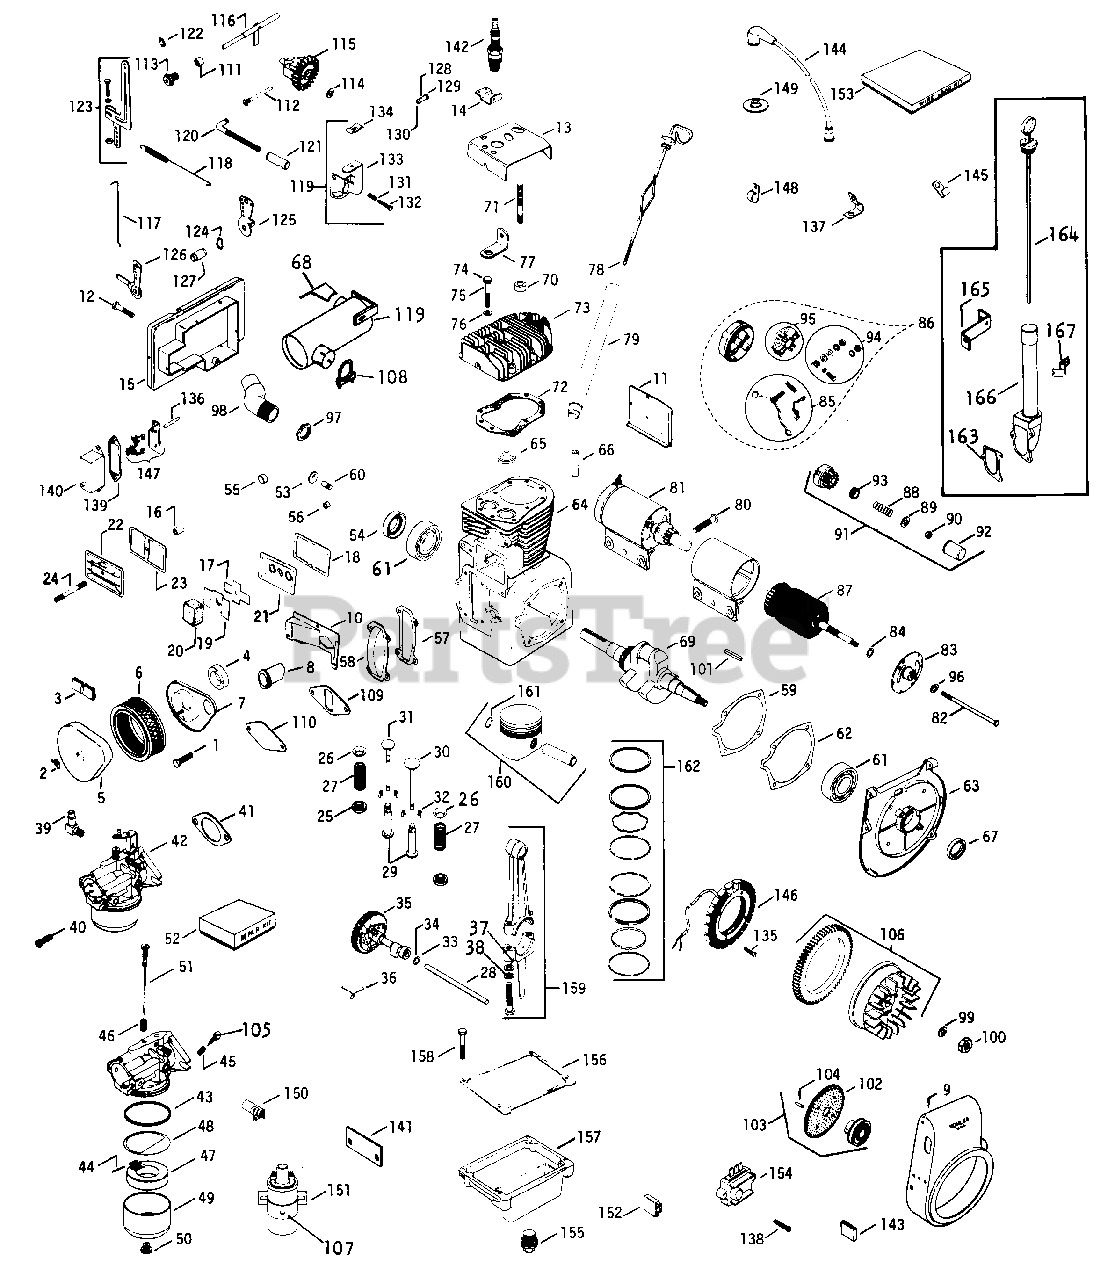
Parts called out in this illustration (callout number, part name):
1	Screw, 10-32 X 1/2 Znd Hex Hd Self Tap
2	Nut, Wing
4	Gasket, Air Cleaner
5	Cover, Air Cleaner
6	Element, Air Cleaner
7	Base, Air Cleaner
8	Tube, Air Cleaner
9	Housing, Blower
10	Baffle, Side
11	Baffle, Cylinder
12	Screw, 1/4-20 X 3/4 Hex Hd
13	Baffle, Head
14	Bracket, Lifting
16	Seal, Breather
17	Reed, Breather
18	Gasket, Cover
19	Baffle, Breather
20	Filter, Breather
21	Plate, Breather
22	Cover, Breather
23	Gasket, Valve Cover
24	Stud, Valve Cover
25	Retainer, Valve Spring
26	Retainer,Valve Spring
27	Spring, Valve
28	Pin, Camshaft
29	Tappet Assy
30	Valve, Intake
31	Valve, Exhaust
32	Keeper, Valve Spring
33	Shim, Camshaft, .005
34	Shim, Camshaft, .010
35	Camshaft Assy
36	Spring, Camshaft Actuating
37	Washer, Connecting Rod
38	Washer, 3/8 Heavy Lock
39	Elbow, Hose Connector
40	Screw, 5/16-18 X 1 Hex Hd Sems
41	Gasket, Carburetor
42	Carburetor Assy
43	Gasket, Fuel Bowl
44	Pin, Hinge
45	Spring, Idle Adjusting Screw
46	Spring, High Speed Needle
47	Float & Lever Assy
48	Gasket, Bowl Baffle
49	Bowl, Fuel
50	Screw w/Gasket, Fuel Bowl
51	Needle, High Speed
52	Kit, Carburetor Repair
53	Plug, 1-1/8 Expansion
54	Seal, Rear Oil
55	Plug, 1/2 Cup
56	Bearing, Crankcase Needle
57	Gasket, Cam Cover
58	Cover, Cam
59	Gasket, Bearing Plate, .010
60	Shaft, Governor
61	Bearing, Crankcase Ball
62	Gasket, Bearing Plate
63	Plate, Bearing
64	Block, Cylinder
65	Insert, Exhaust Valve
66	Guide, Valve
67	Seal, Front Oil
68	Deflector, Exhaust
70	Spacer
71	Stud, Cylinder Head
72	Gasket, Cylinder Head
73	Head, Cylinder
74	Screw, 3/8-16 X 1-1/2 Znd Hex Hd Cap Type 8
75	Screw, 3/8-16 X 1-3/4 Znd Hex Hd Cap Type 8
76	Washer, Head
77	Bracket, Baffle Mounting
78	Dipstick w/Shoulder Mount
79	Tube, Oil Fill w/Shoulder Mount
80	Bolt, Shoulder
81	Starter Assy
83	Cap Assy, Drive End
84	Washer, Armature Thrust
85	Kit, Starter Brush
86	Cap Assy, Commutator End
88	Spring, Anti-Drift
89	Spacer, Stop Gear
90	Nut, 5/16-24 Hex Lock
91	Kit, Starter Drive w/Shim
92	Cover, Dust
93	Spacer
94	Kit, Hardware
95	Kit, Brush Holder
96	Washer, 1/4 Znd Reg Lock
97	Nut, Lock
98	Elbow, Exhaust
100	Nut, 5/8-18 Znd Hex Lock
101	Key, 3/16 X 1-3/8 Sq Parallel
102	Screen, Grass
103	Cup Assy, Flywheel Drive
104	Pin, Flywheel Drive Cup
105	Screw, Idle Adjusting
106	Flywheel Assy
107	Clamp, Ignition Coil
108	Clamp Assy, Muffler
109	Gasket, Pump Cover
110	Cover, Pad
111	Spacer
112	Pin, Governor Stop
113	Bushing, Governor
114	Washer, Thrust
115	Gear, Governor
116	Shaft, Governor
117	Linkage, Choke
118	Spring, Governor
119	Muffler Assy,
120	Rod, Ball Joint
121	Body, Ball Joint
122	Retainer, Throttle Rod
123	Lever, Governor
124	Washer, Tension
125	Lever, Throttle Control
126	Lever, Choke Control
128	Clamp, Swivel Wire
129	Washer, 9/32 X 5/8 X .062 Znd
130	Screw, 1/4-20 X 1-1/4 Hex Hd Sems
131	Spring, Adjusting
132	Screw, Throttle
133	Bracket, Control
134	Clamp, Wire
135	Screw, 10-24 X 3/8 Fil Hd Mach
136	Rod, Breaker
137	Clip, High Tension
138	Screw, 10-24 X 1 Znd Pan Hd Mach
139	Gasket, Breaker Cover
140	Cover, Breaker
141	Bar, Coil Bracket Back Plate
142	Plug, Spark (Champion)
143	Connector
144	Kit, Hi-Tension Lead
145	Clip, Terminal
146	Kit, Stator
147	Breaker & Bracket Assy
148	Clip, Cable
149	Grommet, Spark Plug
150	Condenser, Ignition Coil
151	Coil, Ignition
153	Kit, Wire Lead Cable
154	Regulator Assy
155	Plug, Drain
156	Gasket, Oil Pan Base
157	Base, Oil Pan
158	Screw w/Lock Washer, 3/8-16 X 1-1/2 Znd Hex Hd
159	Rod Assy, Connecting, Std
160	Piston Assy, Std
161	Retainer, Piston Pin
162	Ring Set, Piston, Std
163	Gasket, Oil Fill Tube
164	Dipstick w/o Shoulder Mount
165	Bracket, Dipstick Tube
166	Tube Assy, Oil Fill w/o Shoulder Mount
167	Clamp, Conduit
